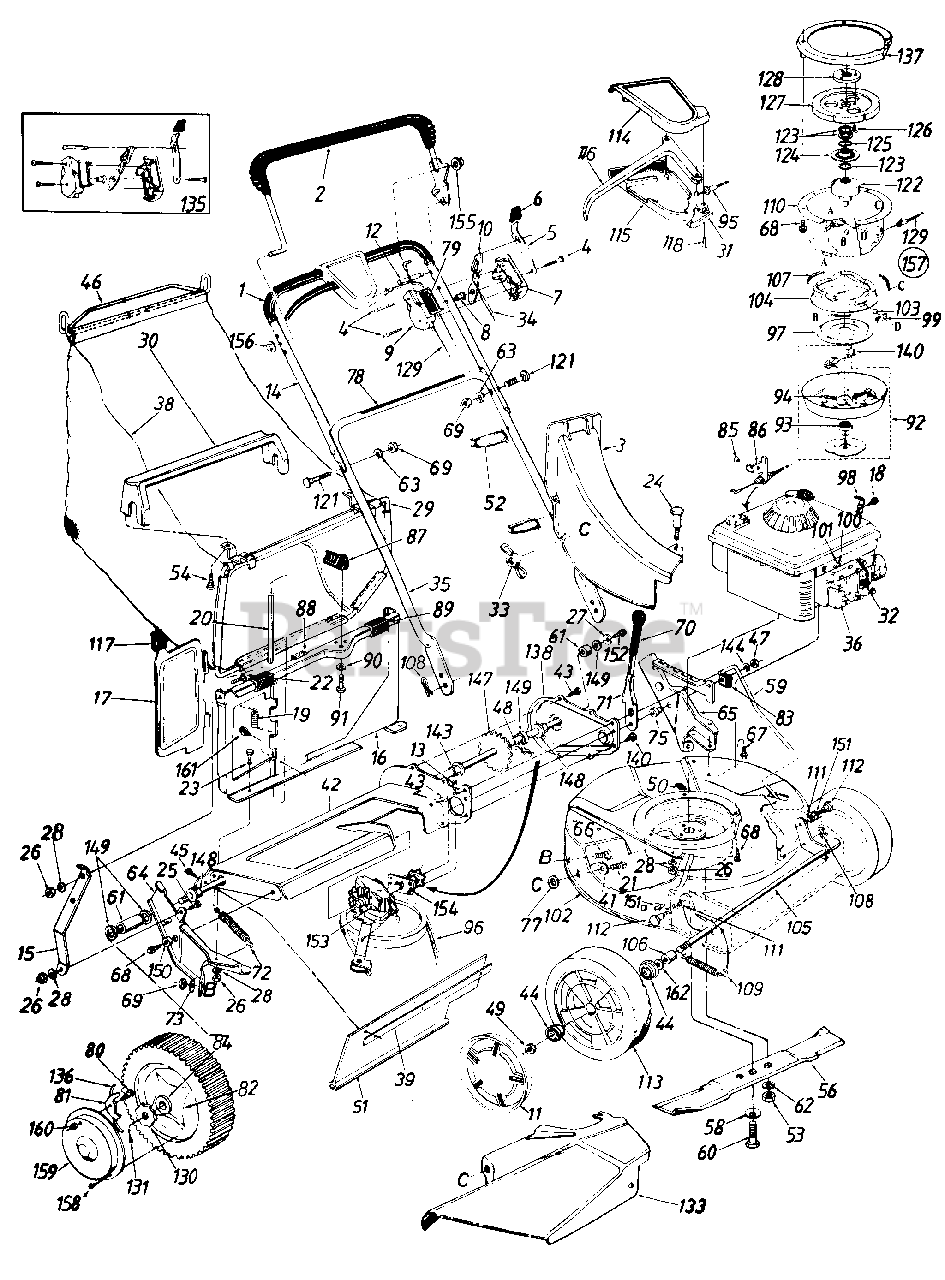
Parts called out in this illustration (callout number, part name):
1	Foam Grip
2	Control Handle Ass'y.-L.H.
3	Top Discharge Chute Ass y.
4	Truss Mach. Scr. #12 x 1.50" Lg.
5	Lockout Spring
6	Spring Lever Knob
7	Control Panel Half
8	Control Disc Pin
9	Clutch Panel Half
10	Throttle Control Lever
11	Hub Cap
12	Lock Pin .314" Dia. x 1.75"
13	Cotter Pin 3/32" Dia. x .75"
14	Upper Handle-Painted
15	Panel Support Brkt.
16	Top Catcher Panel Ass y
17	Top Discharge Door
18	Hex B-Tap Scr. #10 x .38"
19	Torsion Spring
20	Pivot Pin
21	Carriage Bolt 1/4-20 x .62"
22	Truss Mach. Scr. 1/4-20 x .5" Lg.
23	Hex Bolt 1/4-20 x .50" Lg.
24	Shoulder Bolt .312 Dia. x .18 Lg. Special
25	Hex Bolt 1/4-20 x .62" Lg.
26	Hex Nut 1/4-20 Thd.
27	Bell-Wash. 1/4" I.D.
28	L-Wash. 1/4" I.D.
29	Front Grass Catcher Frame
30	Grass Catcher Handle (Black)
31	S.P. Control Cover
32	Spark Plug Insulator
33	Wing Nut
34	Throttle Control Wire 58" Lg.
35	Lower Handle-Painted
36	Engine
38	21" Top Discharge Grass Bag-Black
39	Retaining Strip
41	Fl-Wash. 344" I.D. x .62"
44	Flange Ball Bearing 1/2" I.D.
45	Hex AB-Tap Scr. 1/4 x .62"
46	Upper Bag Handle
47	Hex Patch L-Nut 3/8-24 Thd.
48	#48 Chain 500n Pitch x 30 Links
49	Hex L-Nut 1/4-20 Thd.
51	Rear Flap 3.75" x 17.30" Lg.
52	Cable Tie
53	Hex Nut 3/8-24 Thd. (Grade 8)
54	Hex AB-Tap Scr. #12 x 1.0" Lg.
56	21" Blade
58	Bell-Wash. .46" I.D. x .88" O.D.
59	Height Adj. Rod 19.42" Lg.
60	Hex Bolt 7/16-20 x 2.0'1 Lg. (Grade 5)
61	Spacer .513' I.D. x .7031' O.D. x .69" Lg.
62	L-Wash. 3/8" I.D.
63	L-Wash. 5/16" I.D.
64	R.H. Handle Wheel Brkt. Ass'y.
65	L.H. Handle Wheel Brkt. Ass'y.
66	Carriage Bolt 5/16-18 x .62"
67	Hex Wash. Hd. B-Tap Scr. 5/16-18 x .5" Lg.
68	Hex Wash. Hd. TT-Tap Scr. 3/8-16 x 1.5" Lg.
69	Hex Nut 5/16-18 Thd.
71	Height Adj. Lever
72	Extension Spring .50" O.D. x 3.80" Lg.
73	Bell-Wash. 5/16" I.D.
75	Shld. Spacer .500" Dia. x .100
77	Bolt Retainer 1/4 x .50" O.D.
78	Instruction Label
79	Control Label
80	Shld. Scr. .342" Dia. x .268
81	Pawl
82	Wheel Ass'y. Comp.
83	Clamp
84	Flange Ball Bearing 1/2n I.D.
85	Pop Rivet .156n Dia. x .379n
86	Cable Bracket
87	Grass Catcher Locking Knob
88	Foam Strip, Lg.
89	Panel Clip
90	Spring Wash. .32" I.D.
91	Hex Wash. TT-Tap Scr. 1/4-20 x .75" Lg.
92	Clutch Blade Housing Ass'y.
93	Ball Brg. .669" I.D. x 1.574"
94	Comp. Spring .35" O.D. x 2.0" Lg.
95	S.P Cable x 50" Lg.
96	"V"-Belt
97	Clutch Cone
98	Casing Clamp
99	Ball Block
100	Hex B-Tap Scr. #10 x .62"
101	Casing Clamp
104	Brake Cup Cone
105	Front Axle Ass'y.
106	Sleeve .526" I.D. x .690" O.D. x .880" Lg.
107	Ext. Spring 1.75" Lg.
108	Intern. Cotter Pin 5/16" Dia.
109	Extension Spring .50" O.D. x 3.20" Lg.
110	Clutch Housing
111	Intern. L-Wash. 3/8 I.D.*
112	Shld. Bolt .623" Dia. x .425
113	Wheel Ass'y. Comp.
114	Self-Propelled Control Cover
115	Self-Propelled Control Cover
116	Control Lever
117	Door Grip
118	Fl-"C"-Sunk Hd. Tap Scr. #10 x .75" Lg.
121	Curved Carr. Bolt 5/16-18 x 1.38" Lg.
122	Fixed Pulley Adapter
123	Serrated Washer 1.0" I.D.
124	Serrated Pulley Half
125	Wave Washer 1.005" I.D.
126	Flat HD Tap Scr. 1/4-20 x .625" Lg .
127	Flywheel
128	Flywheel Adapter
129	Control Cable-49" Lg.
130	Ratchet Wheel 1.62" O.D.
131	Cotter Pin 1/8" Dia. x 1.00" Lg.
133	Side Chute Deflector Ass'y.
135	Kit-Control Housing Comp.
136	Spring-Nylon
137	Engine Mounting Plate Cover
143	Hex Flange Brg. .506" I.D.
144	Fl-Wash. .385" I.D. x .87" O.D.
147	Rear Shaft Ass'y. 21.94" Lg.
148	Hex Flange Bearing .506" I.D. Plastic
149	Fl-Wash. .531" I.D. x .930" O.D.
150	Spacer .383" I.D. x .503" O.D.
151	Flanged Nyliner Brg.
152	Hex Bolt 1/4-20 x .62" Lg. (Grade 5)
153	Transmission Comp.
154	Hex Bearing Cup
155	Push Cap
156	Push Cap
157	Blade Brake Clutch Ass'y. Comp.
158	Pan Hd. Tap Scr. #12 x .50" Lg.
159	Hub Cap
160	Hex Ins. L-Nut 1/4-20 Thd.
161	Hex B-Tap Scr. #10 x .38"
162	Fl-Wash. .51" I.D. x .75" O.D.
